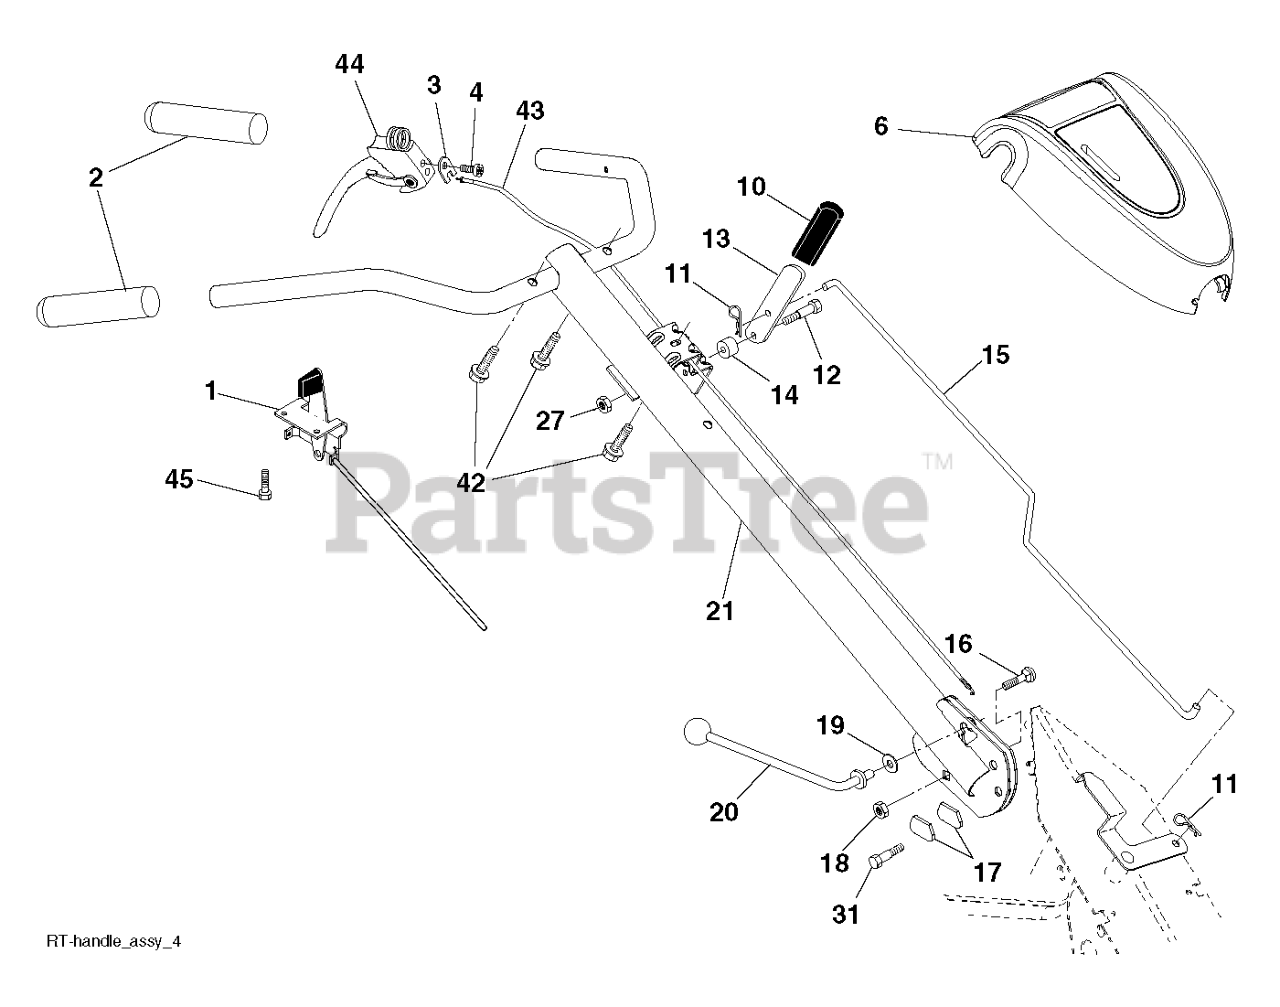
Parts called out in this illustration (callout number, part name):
1	CABLE ASSY THROTTLE
2	GRIP.1X5.06
3	CLIP.RETAINER.CABLE.BZP
4	SCREW.TORX.#10-14X1/2
6	CONSOLE HUSQVARNA W/THROTTLE T
10	GRIP T
11	RETAINER M
12	SHOULDER BOLT ST
13	HANDLE.SHIFT.TILLER.498
14	GROMMET.RUBBER.CRT.TILLER
15	ROD SHIFT RT UNIVERSAL
16	BOLT D
17	LOCK.HANDLE.CRT
19	WASHER CRT
20	LEVER.LOCK.CRT
21	HANDLE.ASM.HUSQ/P.PRO.GREY
27	NUT T
31	BOLT.PIVOT
42	SCREW.#10 X 0.750.BOS
43	CABLE.HANDLE.TINE.CONTROL.CE
44	CONTROL.HANDLE.TWO.FUNCTION.CE
45	SCREW.#10 X 0.500
